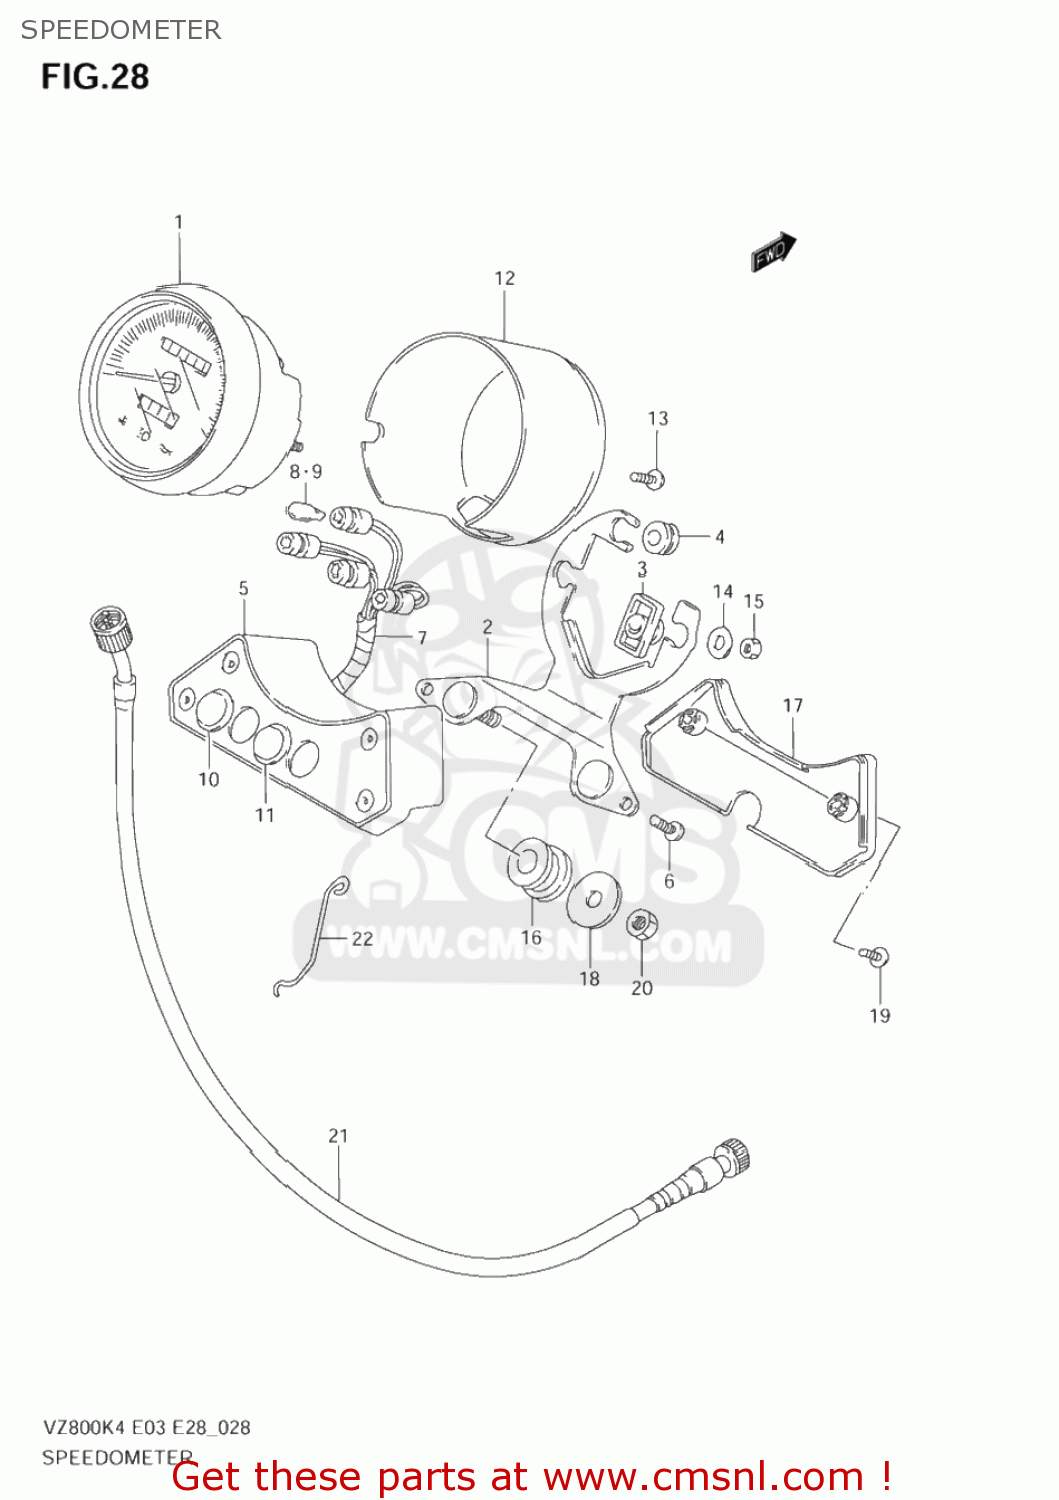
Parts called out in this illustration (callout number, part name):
1	SPEEDOMETER
2	BRACKET
3	CUSHION,DAMPER
4	DAMPER
5	CASE ASSY,PILOT
6	SCREW
7	CORD ASSY
8	BULB(12V1.7W,T6.5)
9	BULB(12V3.4W,T10)
10	LENS,TURNSIGNAL(GREEN)
11	LENS,TURNSIGNAL(GREEN)
12	COVER,UNDER(CHROMUN)
13	SCREW
14	WASHER(5.2X16X1)
15	NUT
16	CUSHION,METER BRACKET
17	COVER,P-BOX
18	WASHER(8.5X28X1.6)
19	SCREW
20	NUT
21	CABLE ASSY,SPEEDOMETER
22	GUIDE,SPEEDOMETER CABLE
